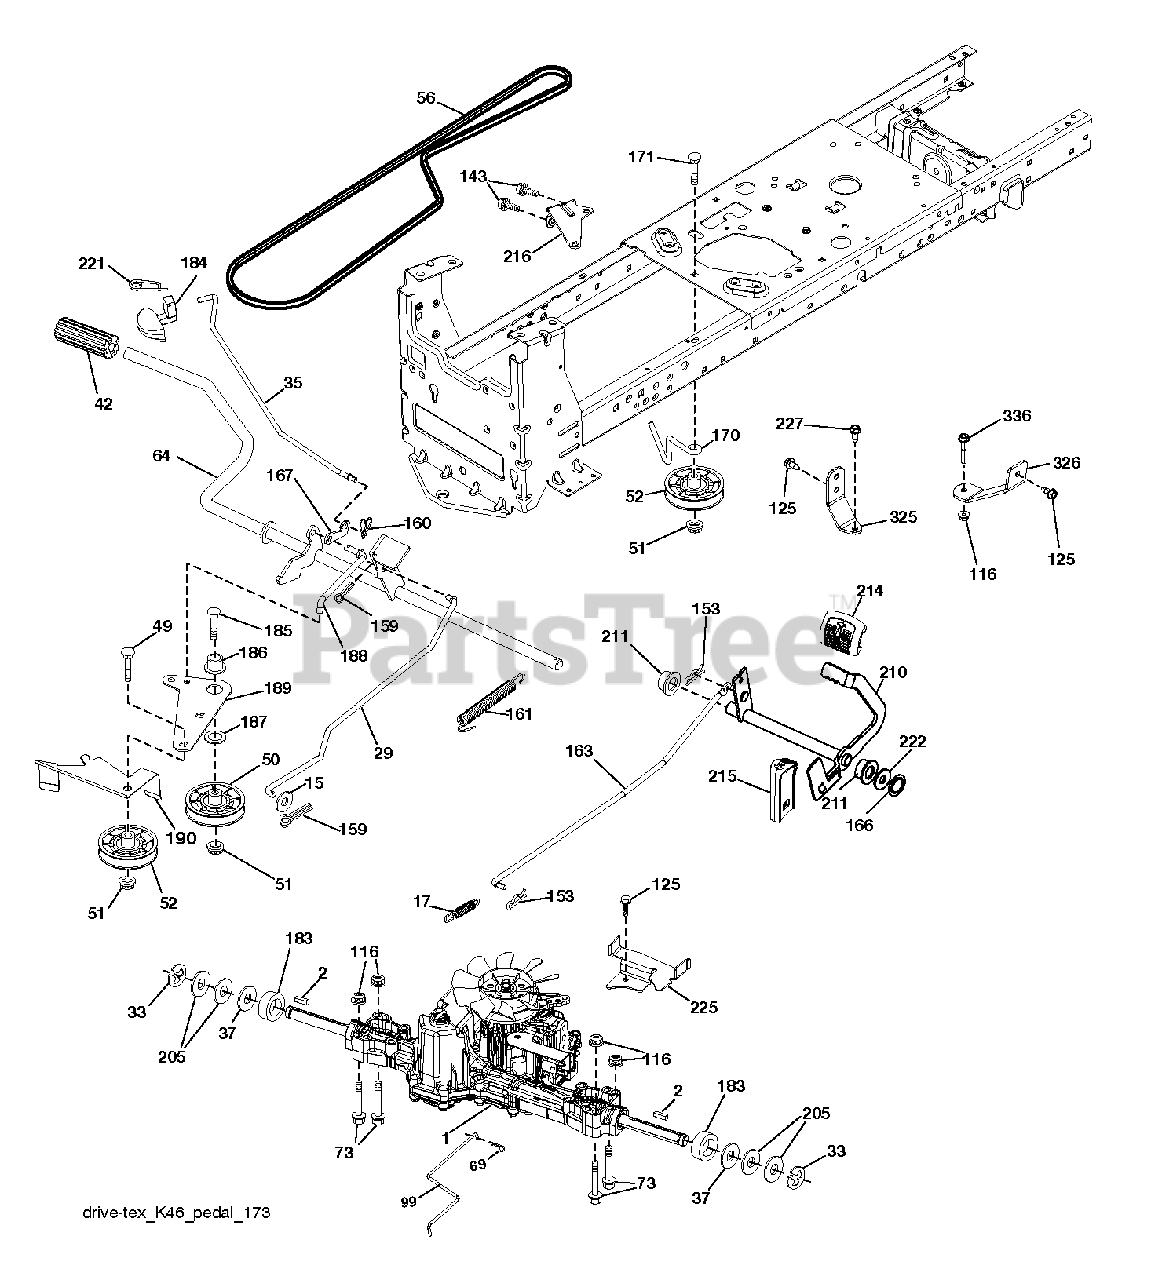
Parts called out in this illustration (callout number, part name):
2	SQUARE KEY
15	WASHER
17	SPRING.BRAKE.VARIATOR
29	BRAKE.VARIATOR.SD3
35	ROD .BRAKE. PARKING. GT. HUSQ.
37	WASHER.HARDENED
42	PEDAL COVER T
50	IDLER.FLAT.910.OFFSET
51	NUT LOCK FLG 3/8-16 UNC
52	IDLER.V-GROOVE.910.OFFSET
56	BELT.DRIVE.MOWER.TEX.42"
64	Variator Shaft, Pedal Cross
69	HAIRPIN.SOFT.ZINC.059X1.125
73	BOLT HEX 5/16-18 GR 5
99	ARM.PIVOTING.TCRD.GEN2.5.BAGGE
116	NUT LOCK HEX FLANGE 5/16-18
125	SCREW
143	SCREW LT
153	RETAINER M
159	COTTER PIN
160	RETAINER CLIP
161	SPRING, RETURN LT
163	ROD.CONTROL.PEDAL.VARIATOR
166	NUT.PUSH.625
167	LATCH.BRAKE.SPRING
170	KEEPER.V-IDLER.CENTER.
183	SPACER AXLE
184	HANDLE.PARKING.BRAKE.H (BLK)
186	SPACER.RETAINER
187	WASHER 12/32X2X10GA
188	LINK.CLUTCH.GROUND DRIVE.LONG
189	BELLCRANK.GROUND.DRIVE.TEX.
190	KEEPER.BELLCRANK.DRIVE
210	WELDMENT.PEDAL.VARIAT
211	BEARING.NYLON
214	PEDAL.FORWARD.PAD.TEX
215	PEDAL.COVER.REVERSE.CRD.X428BK
216	BRACKET.PULLEY.IDLER.W/TEX
221	RETAINER.SPRING.CLIP.H
222	WASHER 21/32 X 1-1/4 X 10 GA.
225	KEEPER.BELT.TRANSAXLE.K46
227	SCREW
325	BRACKET.TRQ.STP.46.20".TIRE.LH
326	BRCKT.PNT.TRQ.STP.46.20TIRE.RH
336	BOLT.5/16-18X1-3/4.FLANGED.HEX
